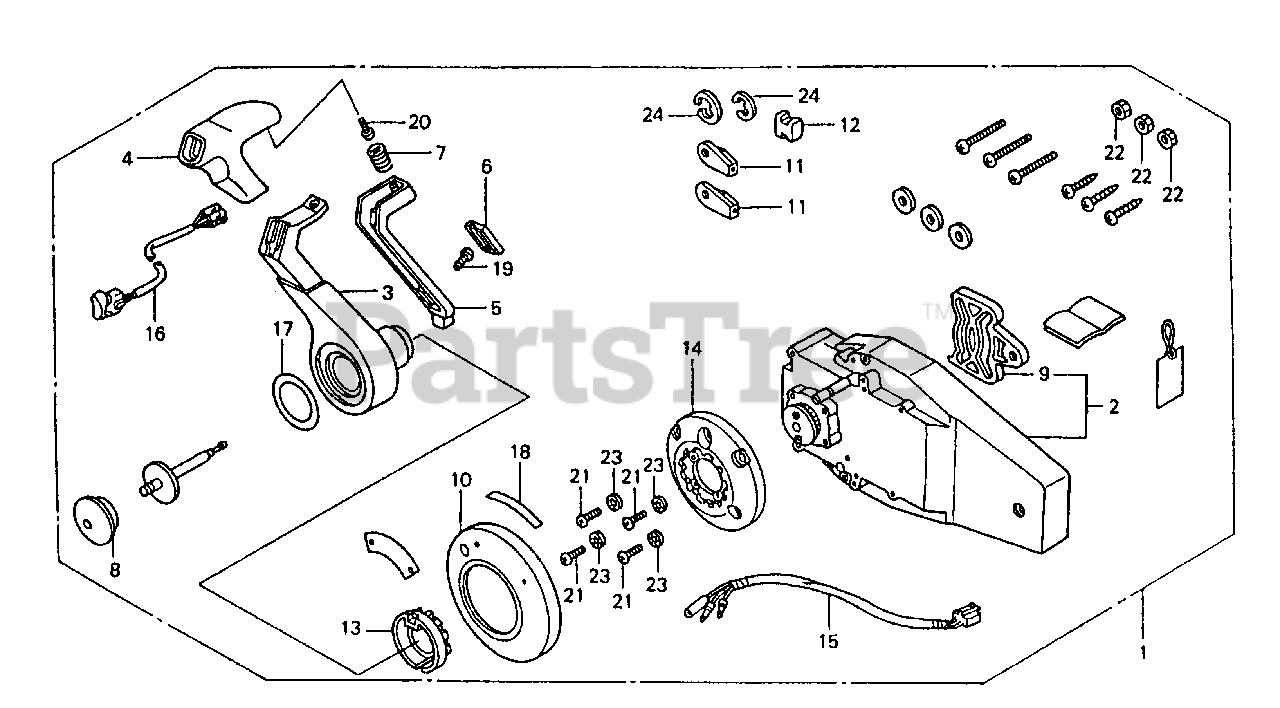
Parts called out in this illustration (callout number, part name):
1	BOX KIT, R. REMOTE CONTROL (FLUSH MOUNT)
2	HOUSING ASSY., R. (INNER) (FLUSH MOUNT)
3	HANDLE, REMOTE CONTROL
4	COVER, GRIP
5	ARM, NEUTRAL LOCK
6	COVER, LOCK ARM
7	SPRING, NEUTRAL LOCK ARM
8	BUTTON, THROTTLE
9	PLATE, DWELL
10	COVER ASSY.
11	CABLE, TERMINAL
12	SPACER, CABLE CLAMP
13	HOLDER, NEUTRAL LOCK
15	SUB-HARNESS C ASSY., POWER TRIM-TILT
16	SWITCH ASSY., POWER TRIM-TILT
17	MARK, HANDLE (FLUSH MOUNT)
18	MARK, FLUSH MOUNT
19	SCREW, TRUSS (4X12)
20	SCREW, PAN (5X10)
21	SCREW, PAN (5X30)
22	NUT, HEX. (6MM)
23	WASHER, LOCK (5MM)
24	E-RING (6MM)
